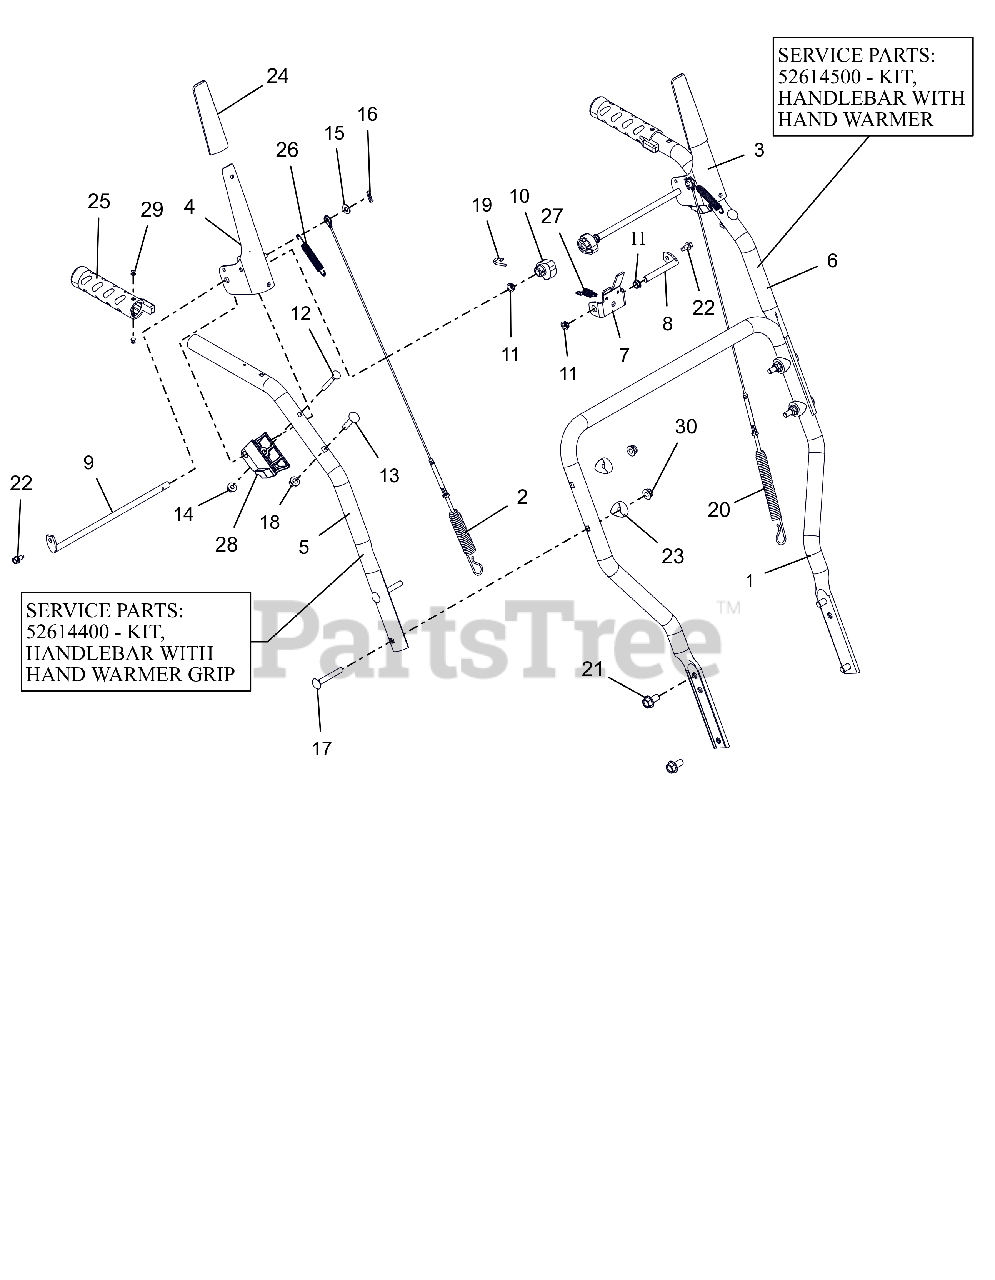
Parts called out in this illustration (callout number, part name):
1	HANDLEBAR, LOWER
2	CABLE, AUGER (DELUXE & PRO)
3	LEVER, CLUTCH-LH
4	LEVER, CLUTCH-RH
5	HANDLEBAR, UPPER - RH
5	KIT, HANDLEBAR HW RH
6	HANDLEBAR, UPPER - LH
6	KIT, HANDLEBAR HW LH
7	BRACKET, INTERLOCK ARM
8	ROD, PIVOT - INTERLOCK
9	ROD, PADDLE MOUNT - PRO
10	CAM, INTERLOCK
11	BUSHING, POLYLINER-.38 SNAPIN
12	BLT-RDHDXLSQNK .25-20X2.0 G5YZ
13	BLT,RHSN .31-18X1.50 G5 ZCC
14	NUT-LK-CTR-FLG .25-20 ZC120
15	WSHR,FLT .281X.625X.065 ZCC
16	PIN, HAIR #178 .06X.77 ZCC
17	BLT, RHSN .31-18X2.25 G5 ZCC
18	NUT-LK-TOP-FLG .312-18 GF ZCC
19	PIN, SPRING CLIP
20	CABLE, UPPER TRACTION
21	BLT-SERHFWH .38-16X.75 YWZC
22	SCR-TAP .25-20X.50 HWH ZCC
23	SPACER, HANDLEBAR
24	SLEEVE, CLUTCH PADDLE-GRAY
25	GRIP,HEATED HANDLE-GRAY
26	SPRING, EXTENSION
27	SPRING-EXT .047X.438X1.45
28	BLOCK, CLUTCH PADDLE
29	RVT-POP #43 .125X.313 STL ZINC
30	NUT,LK-NYL-FLG .31-18 G5ZC120
